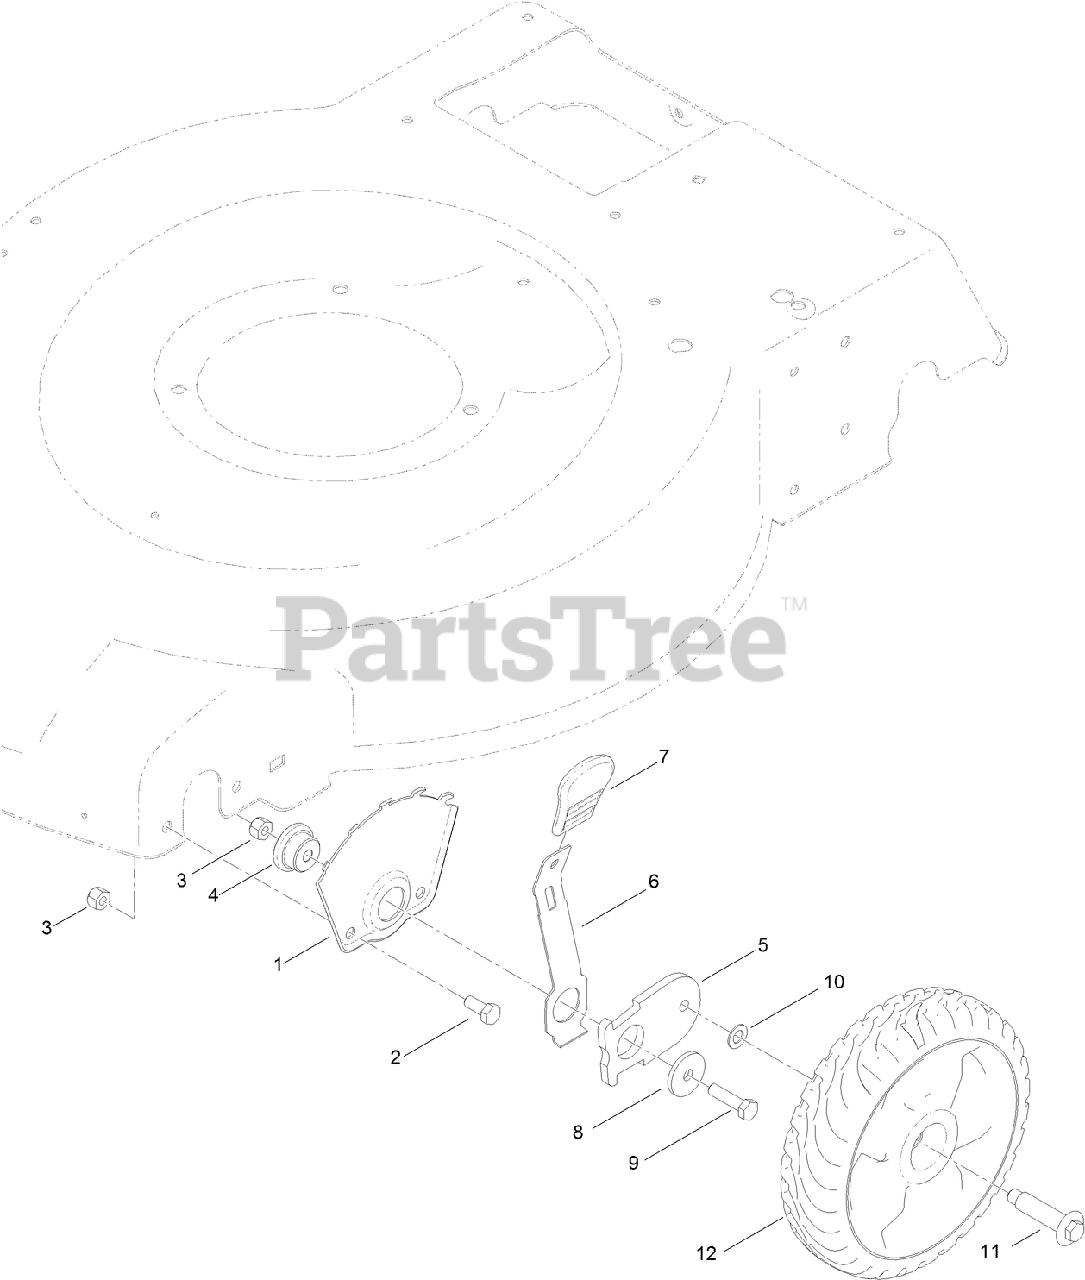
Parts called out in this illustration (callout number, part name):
1	PLATE-HOC, FRONT
2	SCREW-HH
3	NUT-LOCK, NI
4	BUSHING-MOUNT, HOC
6	ARM-SPRING
7	KNOB-HOC
8	WASHER-FLAT
9	SCREW-HH
10	WASHER
11	BOLT-SHOULDER
